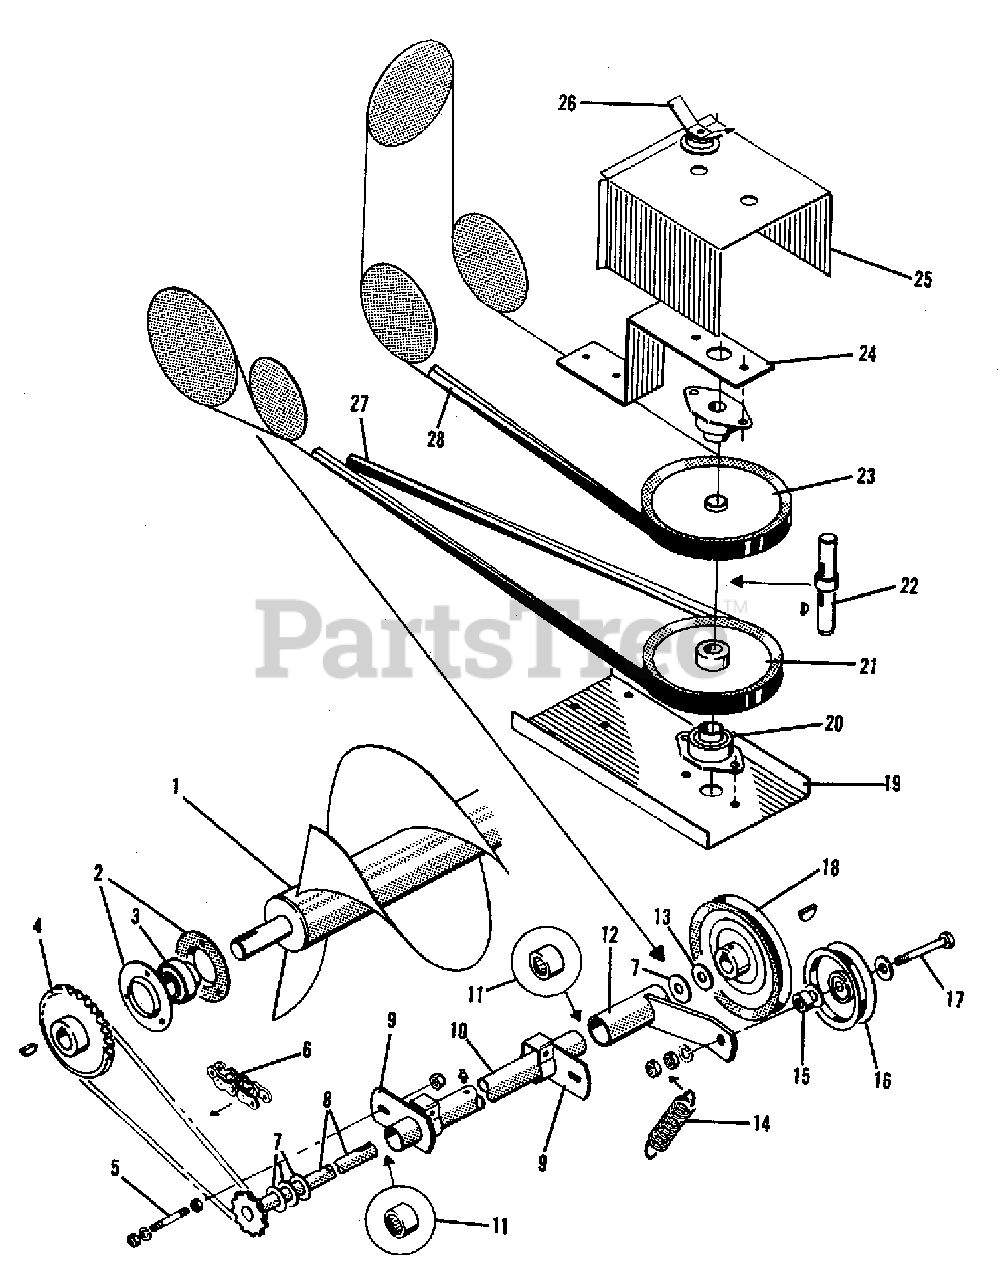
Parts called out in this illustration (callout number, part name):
1	ROTOR ASSEMBLY, 36" Thrower
1	ROTOR ASSEMBLY, 42" Thrower
2	FLANGE, Bearing
2	CAPSCREW, 5/16NC x 3/4
2	LOCKWASHER, 5/16
2	NUT, 5/16NC
3	BEARING, Cartridge
4	SPOCKET, Rotor
4	SETSCREW, 5/16NC x 5/16
4	KEY, Hi-Pro
5	NUT, 3/8NC, Flange Lock
5	NUT, 3/8NC, Lock
5	LOCKWASHER, 3/8
5	NUT, 3/8NC
6	CHAIN ASSEMBLY, Roller #40
8	SHAFT ASSEMBLY, 36" Drive
8	SHAFT ASSEMBLY, 42" Drive
9	SUPPORT ASSEMBLY, Clamping
9	CAPSCREW, 5/16NC x 1-1/2
9	LOCKWASHER, 5/16
9	NUT, 5/16NC
9	CAPSCREW, 3/8NC x 1
9	WASHER, 3/8, Plain
9	LOCKWASHER, 3/8
9	NUT, 3/8NC
10	HOUSING, Bearing 36" Thrower
10	HOUSING, Bearing 42" Thrower
10	FITTING, lube, 1/4NF, String
11	BEARING, ASSEMBLY, Needle
12	SUPPORT ASSEMBLY, Idler
13	washer, 25/32 X 1-1/2 X 10 Ga.
14	SPRING, Idler Pulley
14	PIN, Cotter
15	SPACER, Idler
16	IDLER, Drive Sheave
17	CAPSCREW, 3/8NC x 2-1/2
17	WASHER, Plain
17	LOCKWASHER, 3/8
17	NUT, 3/8NC
17	NUT, 3/8NC, Lock
18	SHEAVE, Sprocket Shaft Drive
18	KEY, #9 Woodruff
19	SUPPORT, Lower Jackshaft
19	CAPSCREW, 3/8NC x 1
19	LOCKWASHER, 3/8
19	NUT, 3/8NC
20	BEARING ASSEMBLY, Flange
20	CAPSCREW, 3/8NC x 3/4
20	LOCKWASHER, 3/8
20	NUT, 3/8NC
21	SHEAVE, Thrower Drive
21	KEY, #9 Woodruff
22	JACKSHAFT
23	SHEAVE, P.T.O. Driven
23	KEY, #9 Woodruff
24	SUPPORT, Upper Jackshaft
24	CAPSCREW, 3/8NC x 1-1/4
24	LOCKWASHER, 3/8
25	COVER, Drive Sheave
26	NUT ASSEMBLY, Wing
26	CAPSCREW, 3/8NC x 1-1/4
26	LOCKWASHER, 3/8
26	NUT, 3/8NC
27	V-BELT, Thrower Drive
28	V-BELT, P.T.O. Drive
